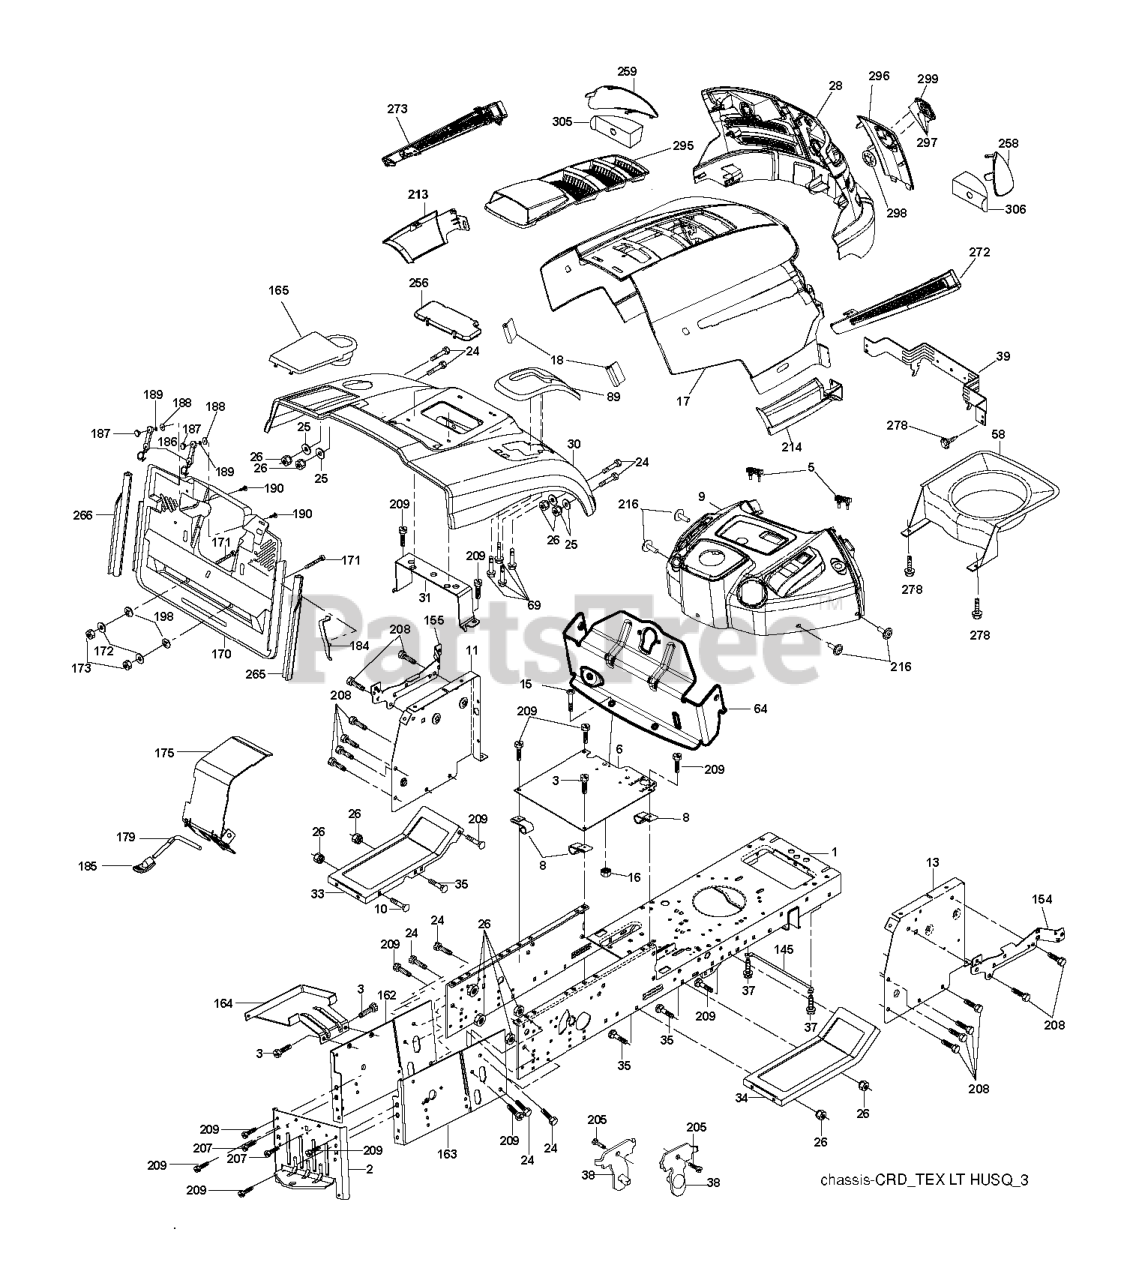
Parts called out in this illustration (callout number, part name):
2	DRAWBAR
3	SCREW 3/8-16X3/4
5	BUMPER DASH
6	PLATE
8	CLIP,INSULATOR
10	BOLT D
11	PANEL.DASH.LH.LTX
13	PANEL ASM, DASH RH
15	Screw, Machine, Truss Head 5/16-18 UNC x 3/4
16	NUT
17	HOOD.HUSQVARNA.LT.ORANGE
18	BUMPER.HOOD.TEX.HUSQVARNA
25	WASHER
26	NUT
28	GRILLE.SVC.HUSQVARNA.LT.GREY
30	FENDER.PNT.CRD.MS-668
31	BRACKET SUPPORT FENDER
33	FOOTREST PNT LH
34	FOOTREST PNT RH
37	Screw 5/16-18 x 1/2 Hex, Self Tapping 5/16-18 x 1/2
38	BRACKET ASM PIVOT MOWER REAR
39	BRACKET PIVOT
69	SCREW.HI-LO.CONSOLE
145	ROD.PIVOT.HOOD
162	BRACKET
163	BRACKET EXTEN CHASSIS RH CRD
165	RP.COVER.BATTERY.CRD.GREY
172	WASHER
175	DOOR TRAP
179	ROD PIVOT FBI
184	BRACKET.ACTUATOR.BAGGER.SRD
186	LATCH ASSY
187	WELDNUT
189	LOCKWASHER #10
190	SCREW
207	SCREW, 5/16-18 X 1/2
208	SCREW 3/8-16X1/2
209	SCREW, 3/8-16X3/4
213	SKIRT SIDE LH
214	SKIRT SIDE RH
216	SCREW HEXWSHR 1/4-20X3/4
256	COVER FENDER CRD
258	LENS.HUSQVARNA LT.RH
259	LENS.HUSQVARNA LT.LH
265	SEALING
266	SEALING
272	VENT SIDE HOOD LH
273	VENT SIDE HOOD RH
278	SCREW.#10 X 0.750.BOS
295	VENT TOP HOOD
296	TRIM
297	CLIP.RETAINER.TINNER.
298	NUT PUSH M
299	RP LOGO
305	INSERT REFLECTIVE
306	INSERT.REFLECTIVE.RH.
